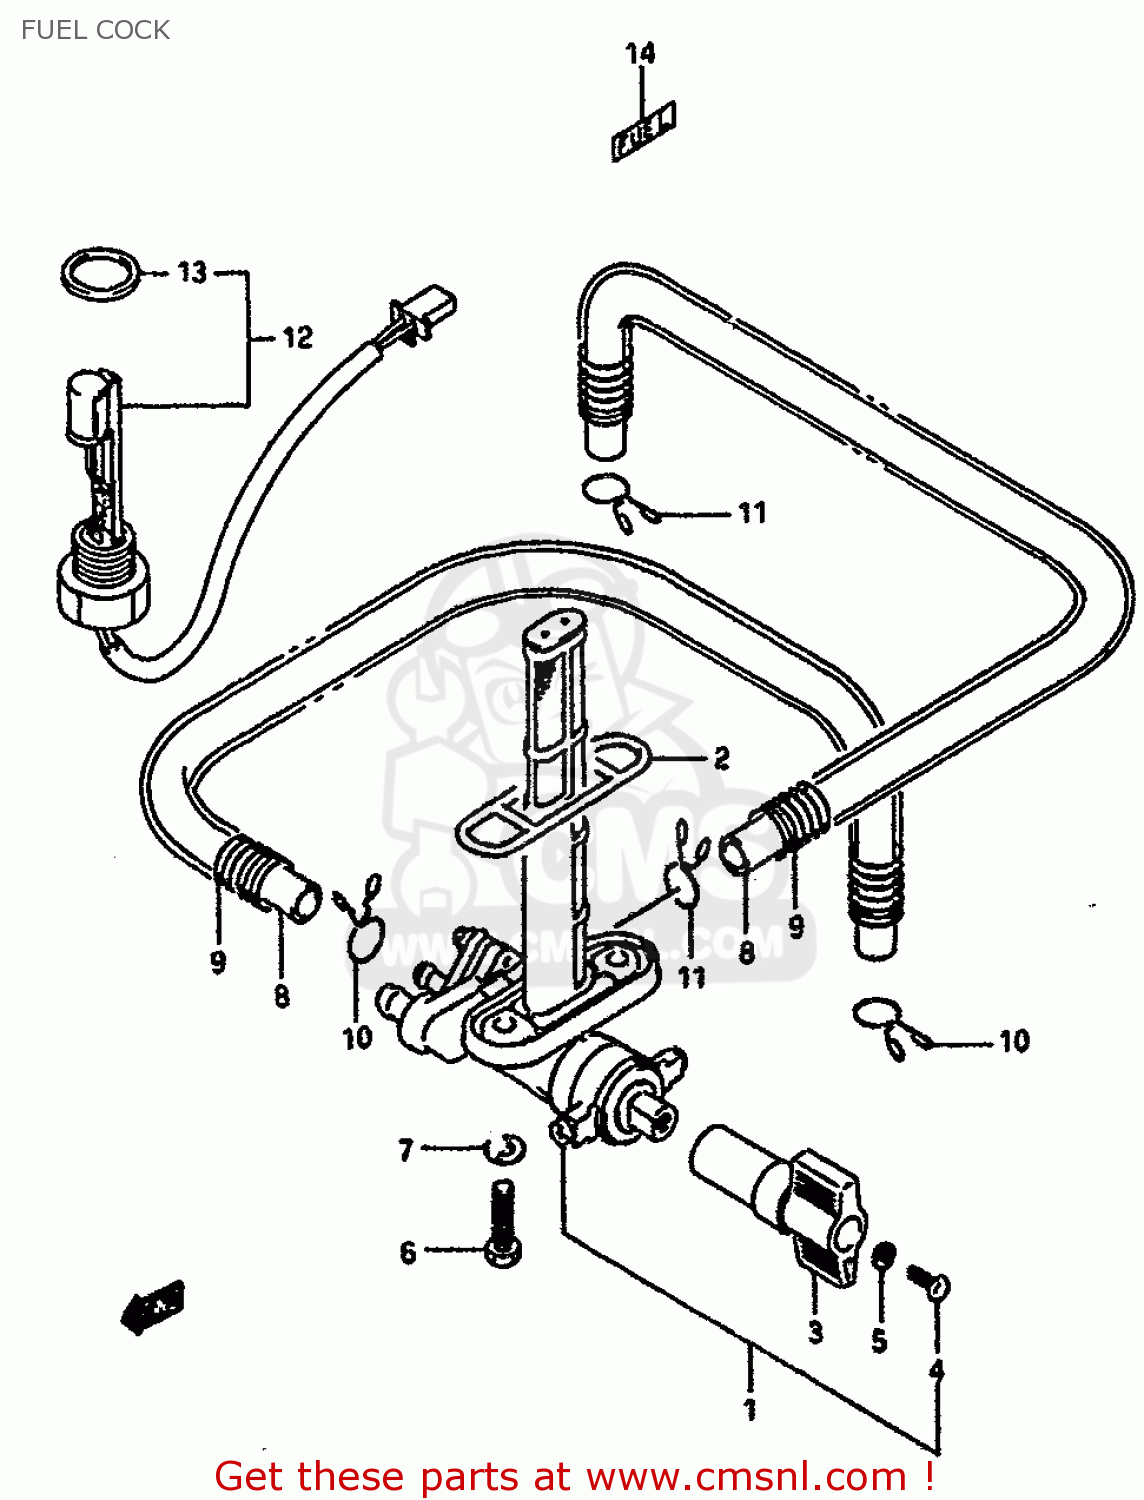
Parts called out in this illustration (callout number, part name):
1	COCK ASSEMBLY,FUEL
2	O RING,FUEL TANK JOINT
3	LEVER,FUEL COCK
4	SCREW
5	LOCK WASHER
6	BOLT(6X20)
7	GASKET(6.4X11.5X0.8) (NAS)
8	HOSE
9	SPRING
10	CLIP
11	CLIP
12	GAUGE ASSEMBLY,FUEL LEVEL
13	GASKET,FUEL LEVEL GAUGE (NAS)
14	LABEL (FUEL)
